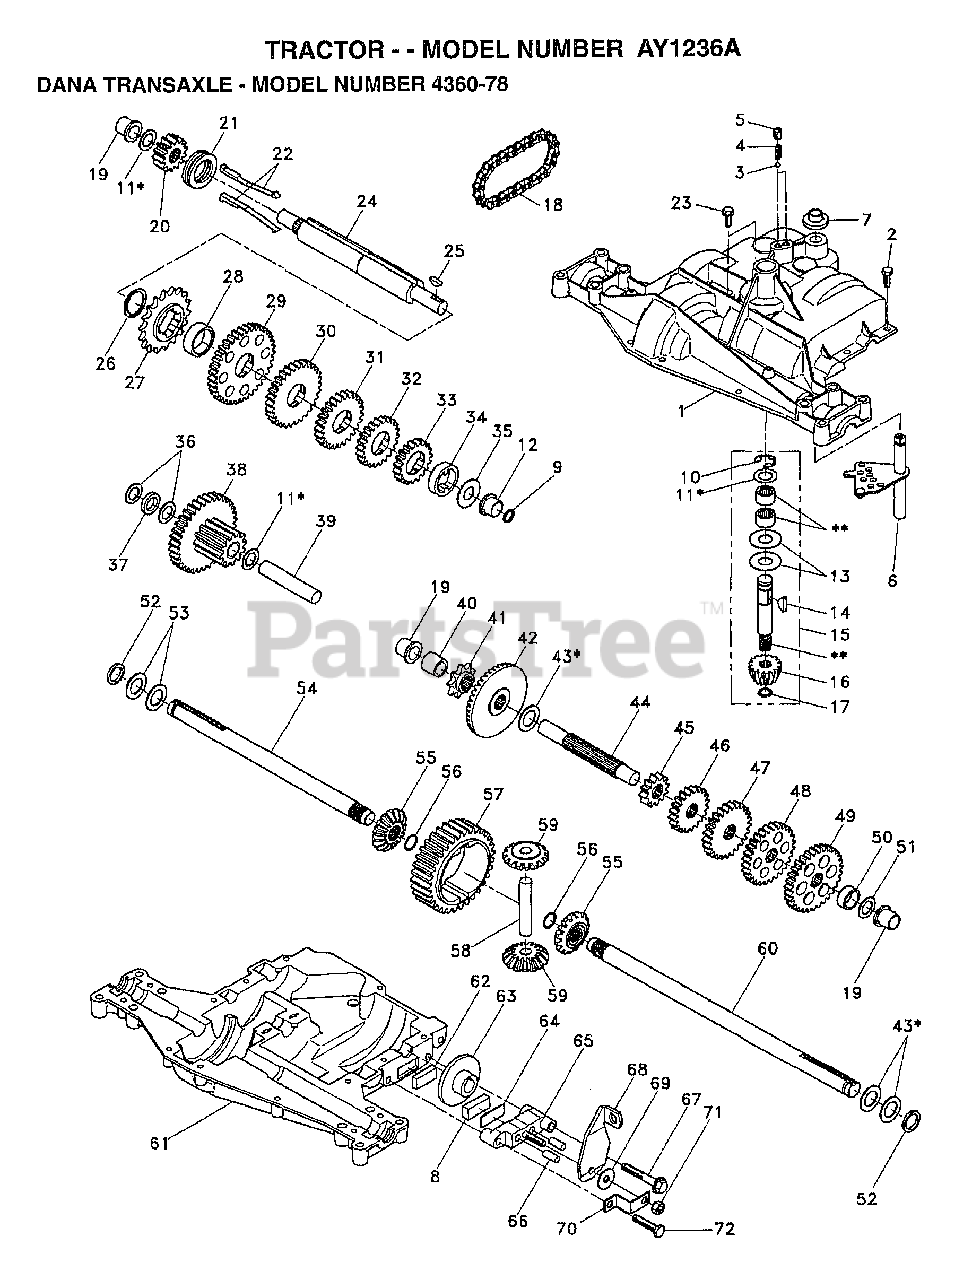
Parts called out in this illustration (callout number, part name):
1	HOUSING UPPER TRN
4	"SPRING, DETENT LT"
5	"SCREW, SET LT"
6	KIT SHIFTER ASM
7	SHIFTER BOOT
8	PUCK T
9	SEAL OIL DANA5416
11	ASM KIT SHIM 4689
13	WASHER T
14	KEY WOODRUFF-DANA
15	AS KIT INPUT SHFT
16	PINION 14T T
17	"RING,RETAINING LT"
18	"CHAIN,24 PTCH LT"
19	BEARING.FLNG.5510
20	GEAR SPUR 14 TTH
21	COLLAR CLUTCH
22	ASM KIT CLTCH KEY
23	SCREW TAP W/SEAL
24	SHAFT INTERM DANA
25	WOODRUFF KEY
26	"RING,RETAINING LT"
27	SPROCKET 18T T
28	SPACER YT
29	GEAR SPUR 37 TTH
31	GEAR 25T LT
32	GEAR SPUR 22 TT
33	SPUR GEAR 19T
34	SPACER
35	"WASHER, PLAIN LT"
36	WASHER 025
37	SPACER
38	ASSM GEAR COMB
39	SHAFT IDLER
40	SPACER T
41	SPROCKET 9T LT
43	ASM KIT SHIM
44	SHAFT T
45	GEAR SPUR 12 TTH
47	"GEAR, SPUR 25T LT"
48	GEAR 28T T
49	"GEAR, SPUR 31T LT"
51	WASHER 060
52	NEOPRENE WASHER
53	WASHER 031
55	GEAR 15T T
56	"RING,RETAINING LT"
58	SHAFT T
59	GEAR 1ST T
61	HOUSING LOWER TNS
62	PUCK T
63	BRAKE DISC. T
64	SPACER LT
66	PIN T
69	WASHER LT
71	NUT.LOCK.5/16-24
72	"SCREW, TAPPING LT"
